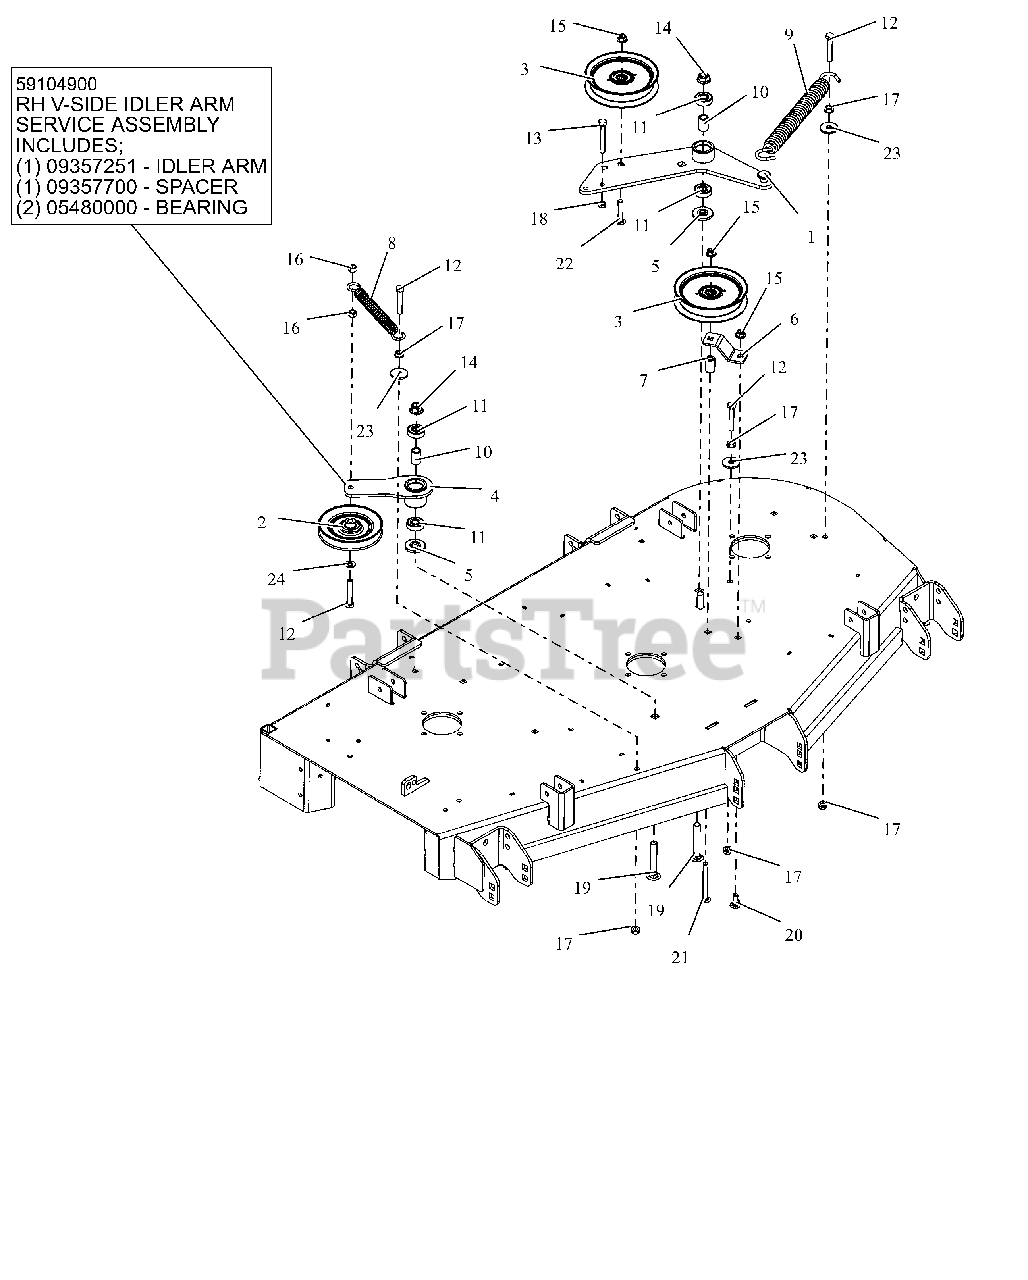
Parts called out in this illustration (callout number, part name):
1	DECK PTO IDLER ARM WLDMT - BLK
2	IDLER, V-5.00"
3	IDLER, FLAT 5.00"
4	DECK RH IDLER ARM WMT - BLK
4	RH V-SIDE IDLER ARM ASSEMBLY
5	SPACER, IDLER ARM
6	PTO FIXED IDLER MTG BRKT -RED
7	BUSHING, SLV .380X.750X1.190
8	SPRING, EXTENSION
9	SPRING, EXTENSION
10	SPACER .510 X .75 X 1.1485
11	BRG-BALL .500X1.38X.437
12	BLT,HEX .38-16X2.25 G5 ZCC
13	BLT, HEX .38-16X2.75 G5 ZCC
14	NUT,NYL-FLG .50-13 GF ZCC
15	NUT,NYL-FLG .38-16 GF ZCC
16	NUT-LK-CTR .38-16 ZC120
17	NUT, SPNLK-FLG .38-16 G5 ZCC
18	NUT-JAM .375-16 G2 ZCC
19	BTL,RHSSN .500-13 X 3.25 G5 ZCC
20	BLT,RHSSN .38-16X1.00 G5 ZCC
21	BLT,RHSSN .38-16X3.50 G5 ZCC
22	BLT,RHSSN.375-16X2.00 G5 ZCC
23	WSHR,FLT .406X1.375X.135 ZCC
24	WSHR,FLT .406X.812X.065 ZCC
